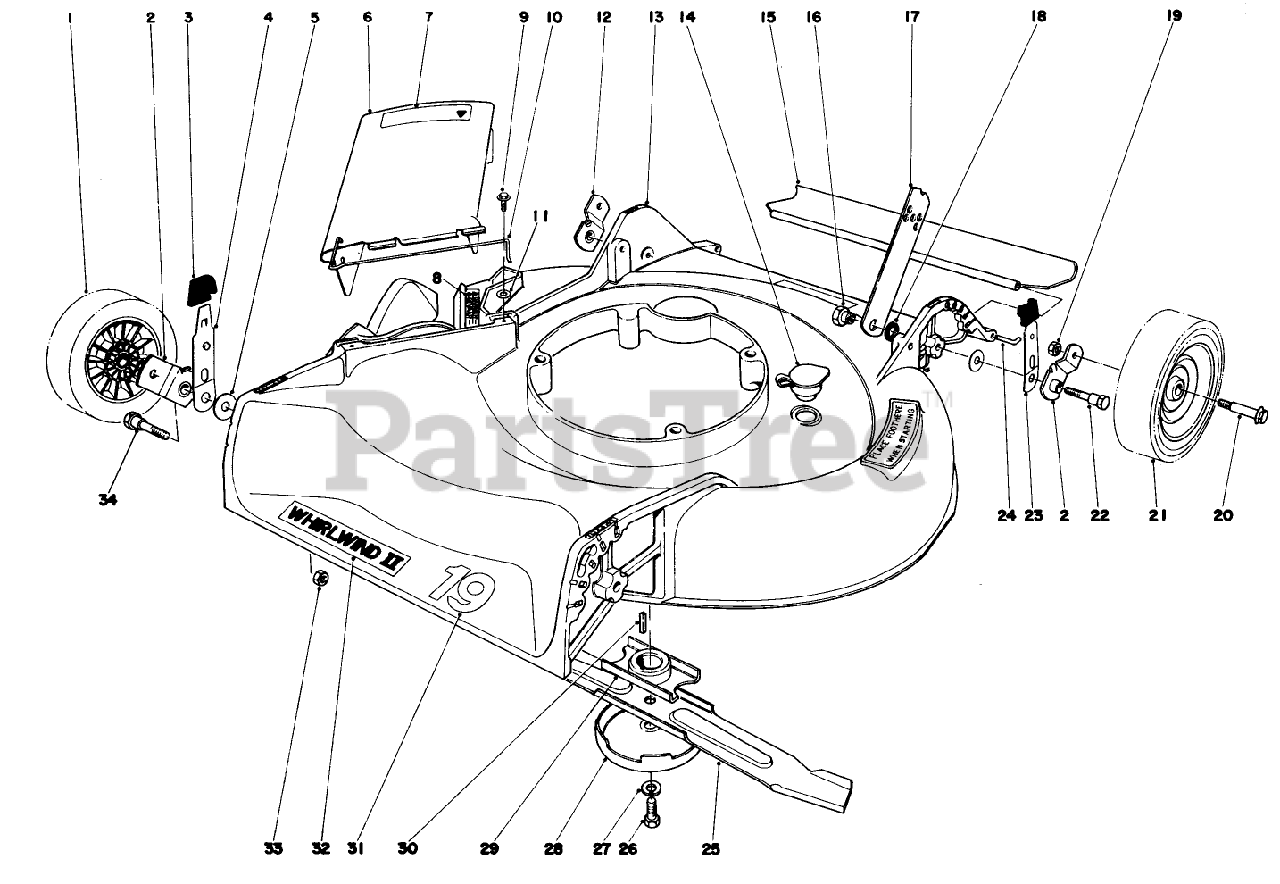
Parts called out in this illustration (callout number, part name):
1	Wheel Tire Assembly
3	KNOB-ARM
4	SPRING ARM ASM
5	Washer
9	SCREW
11	WASHER-FLAT
13	Housing (Model 16009)
14	WASHOUT PLUG
15	SHIELD - TRAILING
16	HANDLE PIVOT NUT
18	HANDLE LATCH SPACER
21	Wheel Tire Assembly
22	PIVOT SCREW
27	WASHER-LOCK
30	KEY-SQUARE
34	PIVOT SCREW
